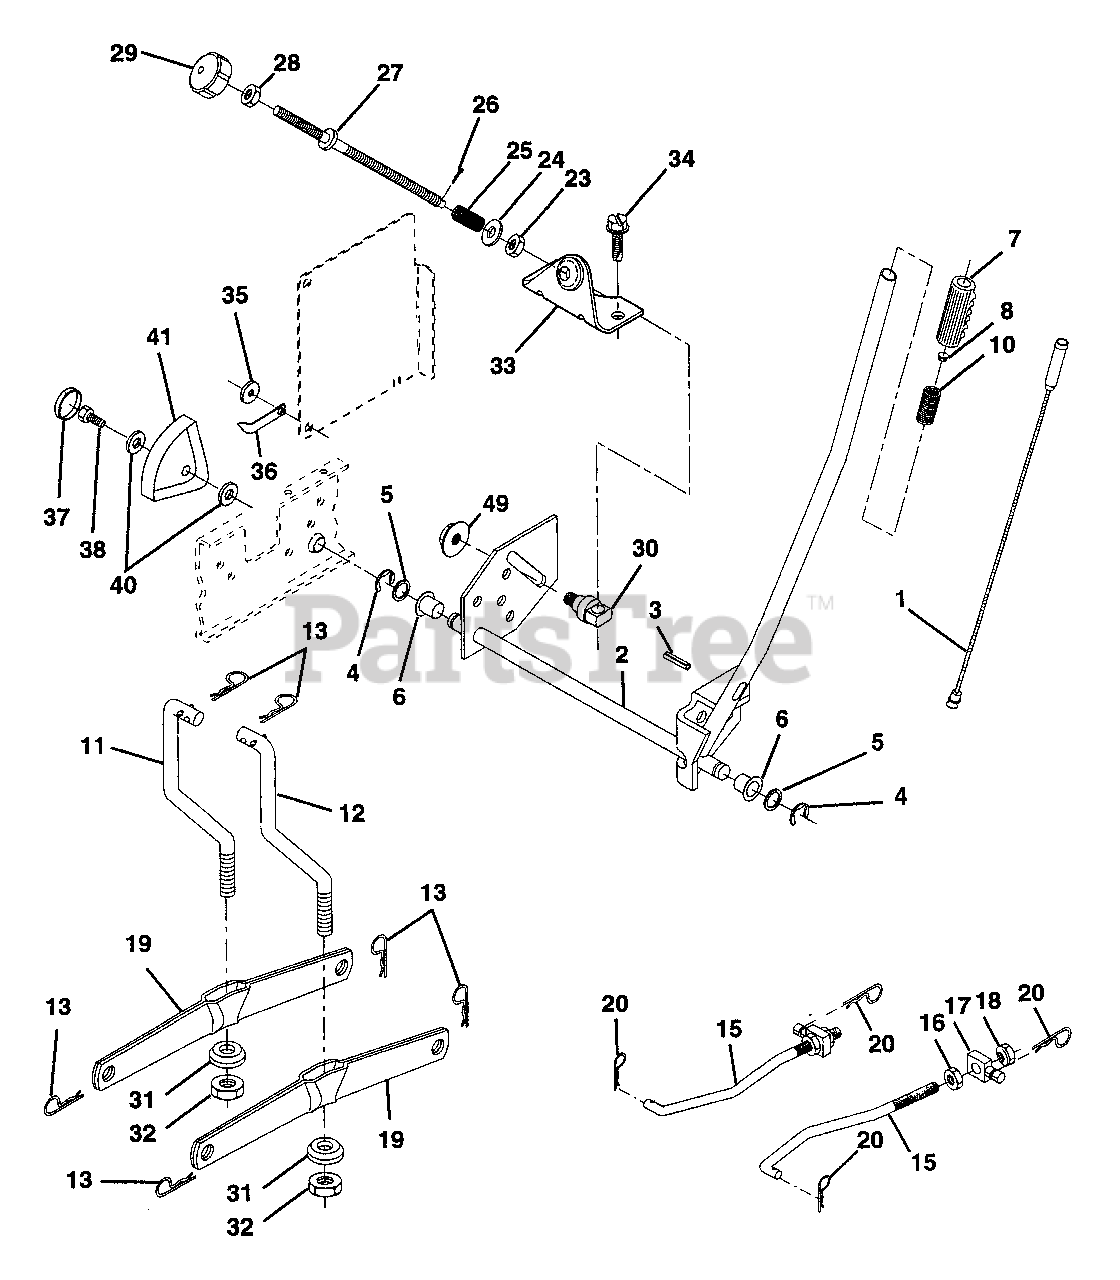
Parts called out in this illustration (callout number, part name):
1	Wire Asm Inner W/plunger 17.32
2	Shaft Asm Lift RH w/Inf
3	Pin Groove 1 500 Zinc
4	E Ring #5133-62
5	Washer 21/32 X 1 X 21 Ga
6	Bearing Nylon Blk 629 Id
7	Grip Handle Fluted Blk
8	Button Plunger Black
10	Spring Cprsn 3 750 Oiled
11	Link Lift LH
12	Link Lift RH
13	Retainer Spring
15	Link Front
16	Nut Jam Hex 1/2-13 Unc
17	Trunnion Blk Zinc
18	Nut Lock W/wsh 1/2-13unc
19	Arm Suspension Rear
20	Retainer Spring
23	Nut Special
24	Washer 13/32 X 5/8 X 16 Ga
25	Spring Compression Inf. Hgt.
26	Pin Cotter 3/32 X 1/2
27	Rod Adj Lift Zinc 7.49 Wrk Lg
28	Nut Hex Jam 3/8-16 Unc
29	Knob Inf 3/8-16 Unc Blk W/sym
30	Trunnion Inf Height
31	Bearing Pvt Lift Spherical
32	Nut Crownlock 3/8-24
33	Bracket, Stop Inf. Hgt.
34	Screw, Thdrol 3/8-16 x 1/2 Ty-TT
35	Washer Nylon .44 x .75 x .032
36	Pointer Height Indicator
37	Plug Hole Blk 1.485/1.515
38	Screw Thdrol 5/16-18 x 3/4 TYT
40	Washer 11/32 x 1-1/2 x 10 Ga.
41	Scale Ind. Height Blk
49	Nut Hex Flange Lock
